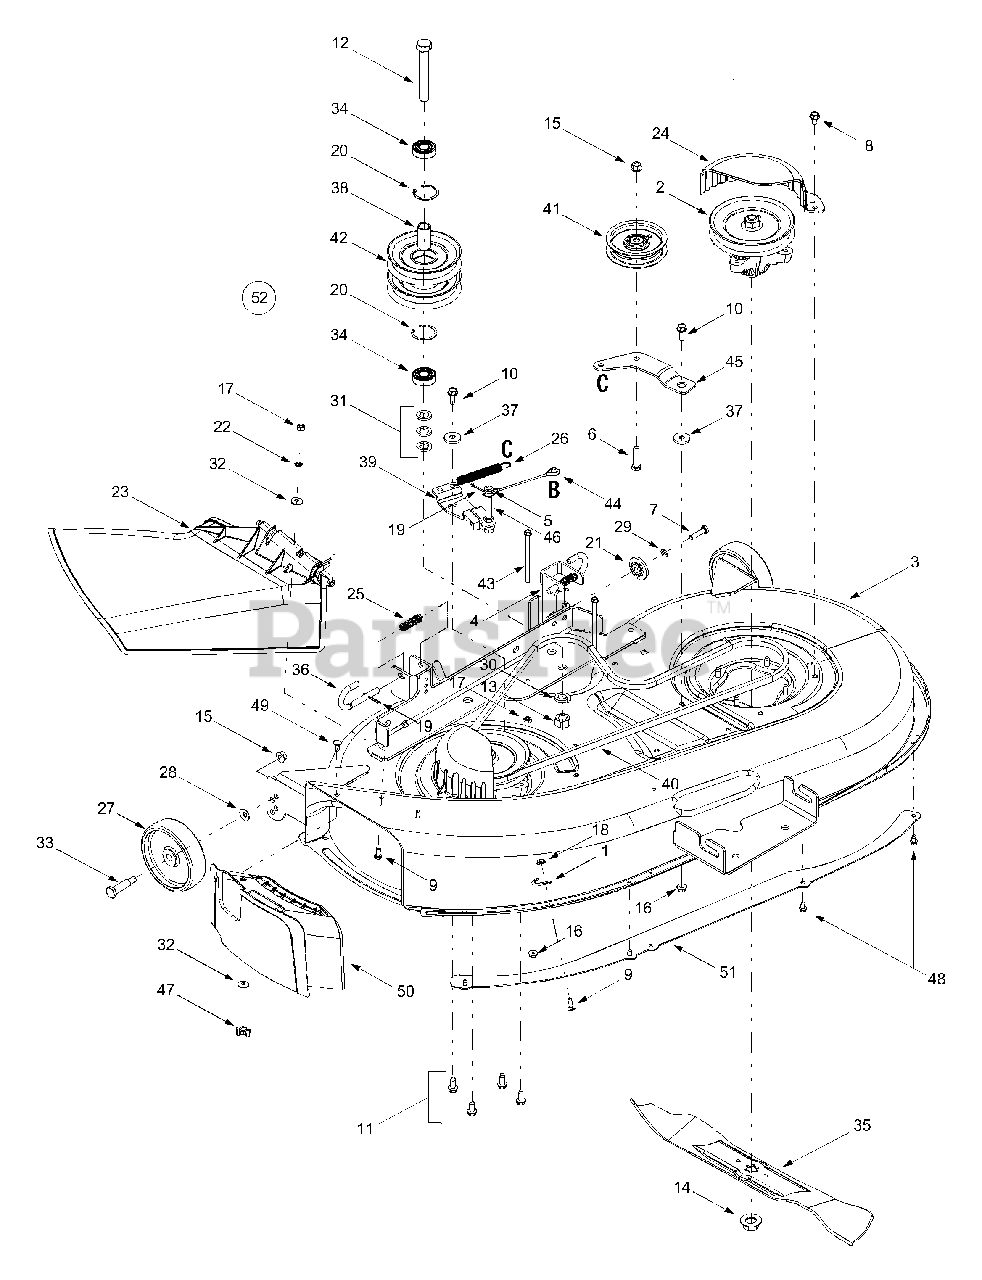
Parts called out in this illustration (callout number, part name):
1	Retainer Hook
2	Spindle Assembly, 5.75 Dia. (w/o grease fitting)
5	Flat Washer, .385 x .62 x .063
6	Hex Cap Screw, 1/4-20 x 1.5
7	Hex Cap Screw, 5/16-18 x 1.25
8	Self-tapping Screw, 5/16-18 x .625
9	Hex Cap Screw, 1/4-20 x .62
10	Hex Head Washer Screw, 5/16-18 x .875
11	Self-tapping Screw, 5/16-18 x .75
12	Hex Cap Screw, 5/8-18 x .875
13	Hex Nut, 5/8-18
14	Hex Flange Nut, 5/8-18
15	Flange Lock Nut, 3/8-16
16	Flange Lock Nut, 5/16-18
17	Hex Nut, 1/4-20
18	Hex Flange Lock Nut, 1/4-20
19	Cotter Pin, 1/8 x 1.25
20	Internal Snap Ring
21	Deck Adjustment Gear
22	Push Nut. .25 x .5
23	Side Discharge Chute Assembly
24	Belt Cover
25	Compression Spring, .406 x .531 x 1.75
26	Extension Spring, .50 x 4.74
27	Deck Wheel, 5 x 1.38
28	Bell Washer, .401 x .87 x .063
29	Lock Washer, 5/16
30	Lock Washer, 5/8
31	Flat Washer, .64 x 1.0 x .12
32	Bell Washer, .265 x .75 x .062
33	Shoulder Screw, .498 x 1.53
34	Bearing, .625 x 1.574 x .470
35	Three-in-one Blade, Star Center, 21.23"
36	Deck Release Pin
37	Shoulder Spacer, .625 x .324
38	Spacer, .635 x .88 x 1.72
39	Deck Brake Assembly
40	Deck Belt
41	Idler Pulley, 3.5
42	Double Pulley, 5.0
43	Self-tapping Screw, 1/4-20 x 4.0
44	Brake Cable, 5.05
46	Pin, 3/8-16, 3/8 x 3.27
47	Wing Nut, 1/4-20
48	Self-tapping Screw, 1/4-20 x .5
49	Carriage Screw, 1/4-20 x .62
50	Mulch Plug
